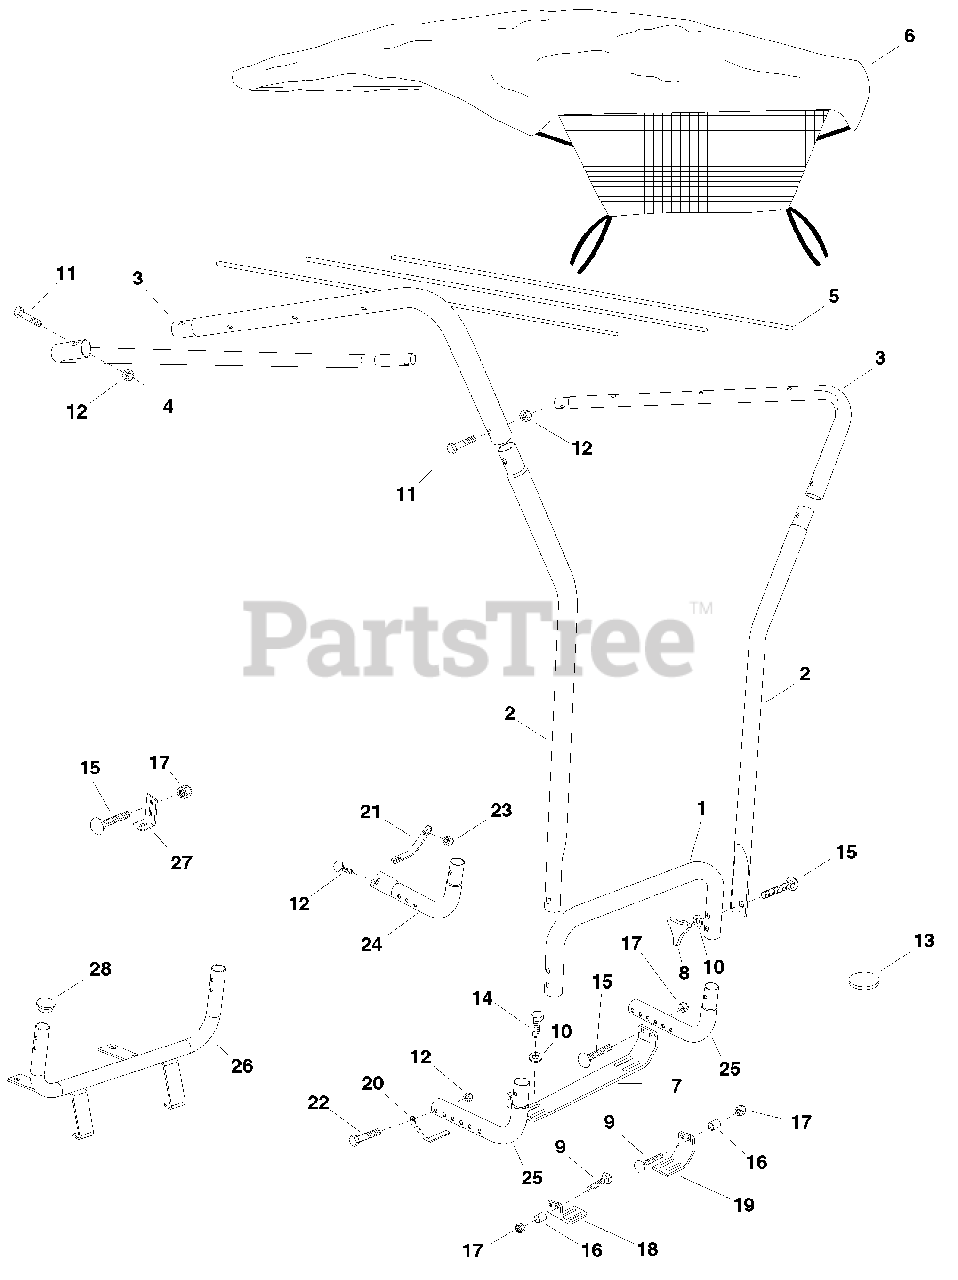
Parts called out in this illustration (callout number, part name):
1	Base Top Tube
2	Upright Tube
3	Top Tube
5	Support Rod
6	Vinyl Canopy
7	Base Bracket
8	Plastic Knob
9	Carriage Bolt, 5/16-18 x 2-3/4"
10	Flat Washer, 5/16"
11	Hex Bolt, 1/4-20 x 1-1/2"
12	Nylock Nut, 1/4-20
13	Adhesive Pad
14	Hex Bolt, 5/16-18 x 1"
15	Carriage Bolt, 5/16-18 x 2"
17	Nylock Nut, 5/16-18
18	Left Base Bracket
19	Right Base Bracket
20	Left Support Bracket
21	Right Support Bracket
22	Hex Bolt, 5/16-18 x 2"
23	Carriage Bolt, 1/4-20 x 1"
24	Base Leg Tube
25	Base Leg Tube
26	Base Bracket Assembly
27	Rear Support Bracket
28	Plastic Cap
